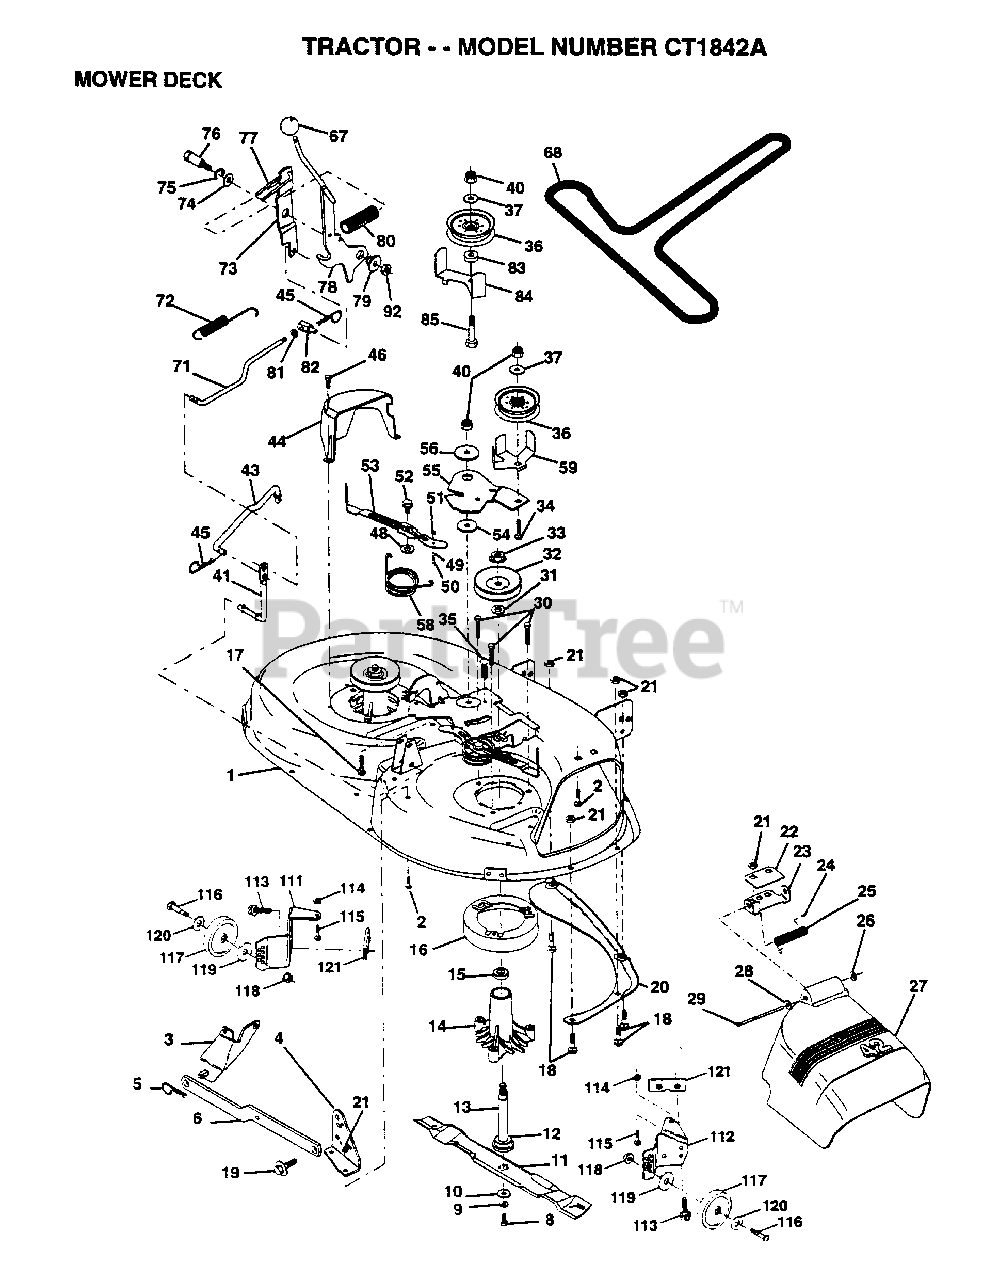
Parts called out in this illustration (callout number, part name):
1	DECK.WELD.42.
2	BOLT
3	BRKT ASM SWAY BAR
4	BRKT DECK SW BAR
8	BLADE BOLT
10	WASHER.HARD.BLADE
11	"BLADE.42"" HIPERF"
12	BEARING.BALL
14	HSG ASM MANDREL
15	BEARING
16	STRIPPER RND MWR
17	BOLT RDHD 3/8-16
18	BOLT
19	BOLT SHD 5/16-18
22	STIFFENER BRKT
23	DEFLECTOR BRKT
24	CAP-SLEEVE LT
25	SPRING TORSION
26	NUT PUSH M
27	DEFLECTOR.SHIELD
28	WASHER
29	HINGE ROD
31	WASHER
34	BOLT
35	XMAS TREE FASTNER
36	FLAT IDLER PULLEY
37	WASHER
41	PIVOT ROD
43	ROD CLUTCH W/NIBS
44	GUARD MAND LH BLK
45	RETAINER M
46	SCREW.1/4-20X5/8
48	HARD SMALL WASHER
50	SHOULDER BOLT
51	LOCKNUT
52	BOLT.SHLD.5/16-18
53	BRAKE PAD ARM ASM
54	HARDENED WASHER
56	SPACER RETAINER
58	SPRING TORSN BRAK
59	GUARD IDLER TUV
67	KNOB T(3/8 HOLE)
68	BELT.V.T-PATH
71	ROD CLUTCH 38/42
72	RETURN SPRING
73	CLUTCH ARM SECOND
74	WASHER
75	RING
76	SHOULDER BOLT
77	SPRING KEEPER
79	BUSHING
81	NUT
82	TRUNION ADJ
83	WASHER
85	BOLT
92	NUT
113	SCREW
116	BOLT M
117	WHEEL.GAGE.BLK.PL
118	LOCKNUT
119	WASHER
120	WASHER
121	BRACKET.EXTRD.GWL
